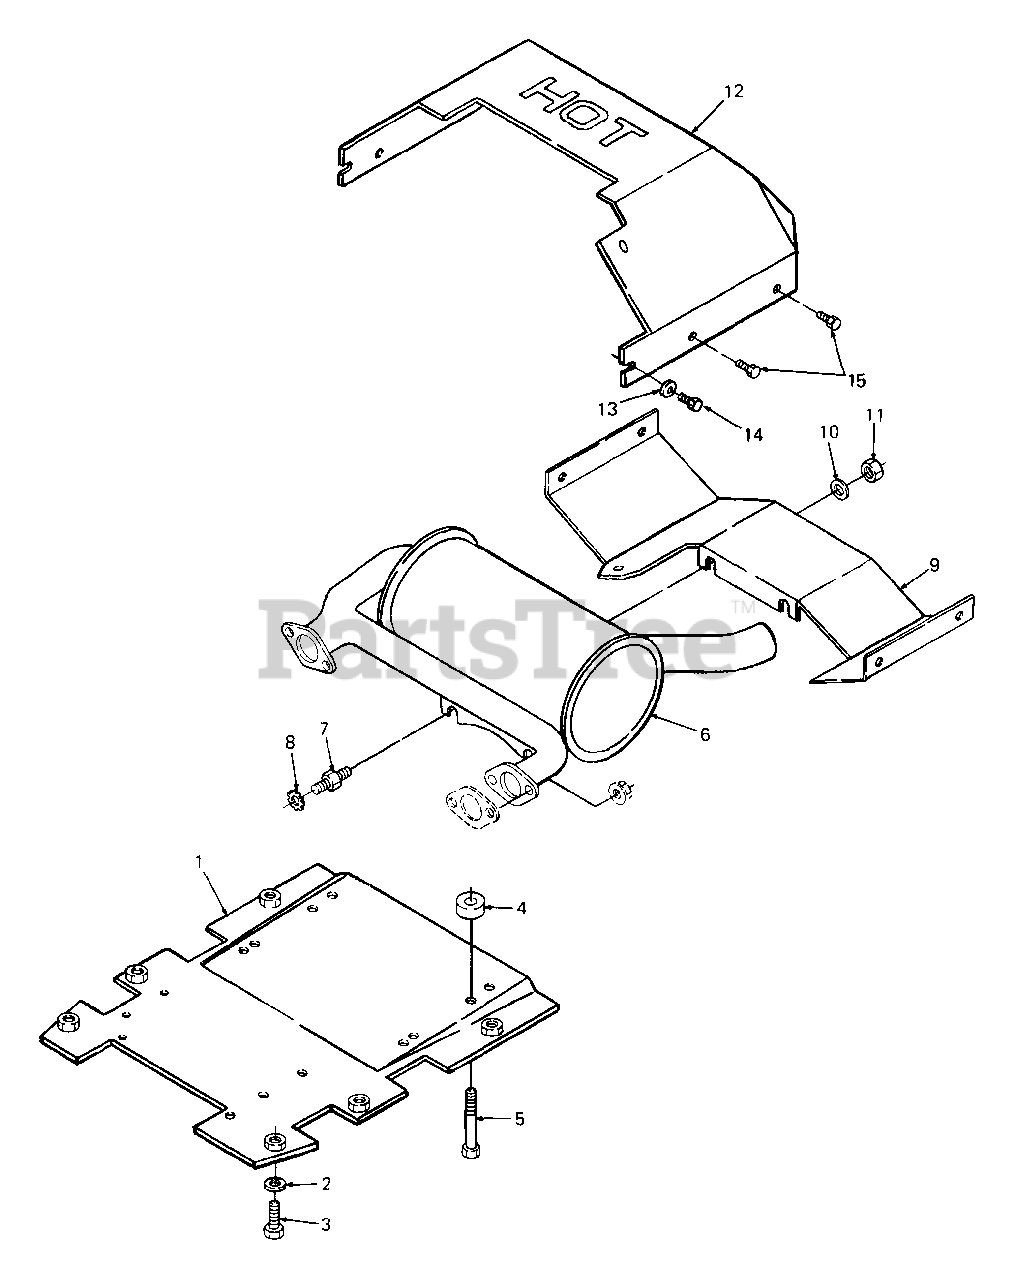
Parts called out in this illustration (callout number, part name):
3	Bolt, Patch, 3/8-16 x 1.0 Lg
4	Spacer, .423 x 1.0 X.469 Lg
5	Bolt, Patch, 3/8-16 x 2.25 Lg
7	Stud, 7/16-14 UNC-2A Thd
8	Washer, External Lock, .45 X.75 x .03 Thk
11	Nut, Hex, 7/16-14 GR5
12	Duct, Engine
13	Washer, Flat, .281 x .50 x .063 Thk
14	Bolt, Hex, M6-1.0 x 10 MM Lg GR5
15	Screw, Hex Wash Hd Tapp, #10x .50 Lg
